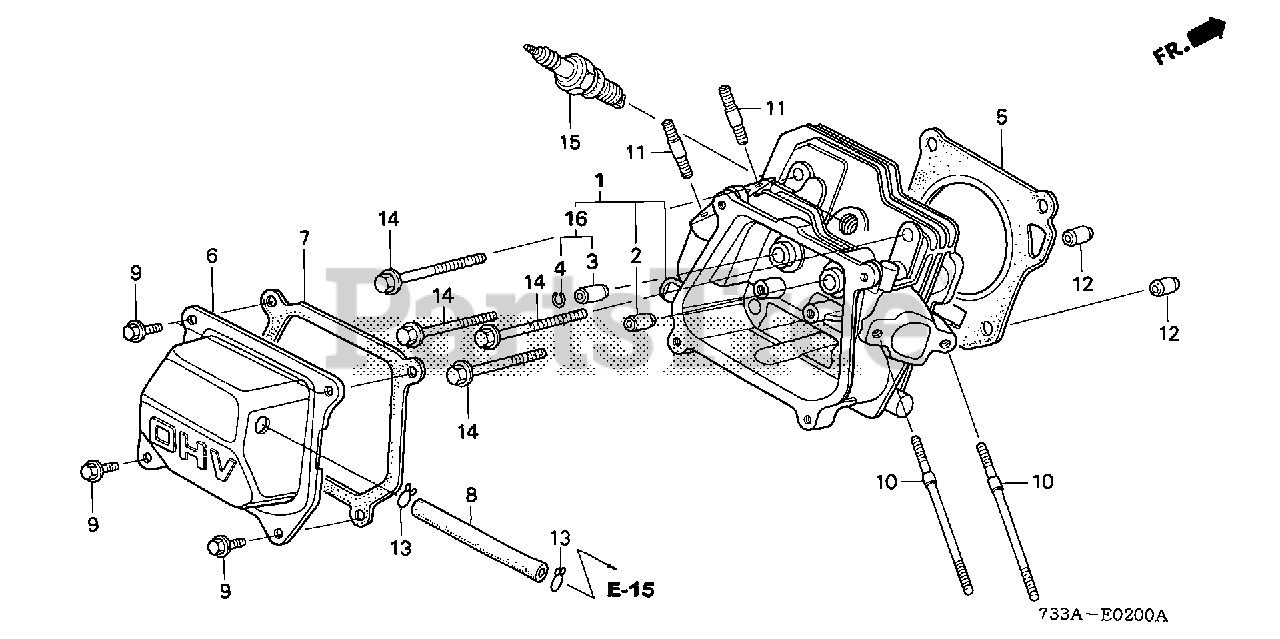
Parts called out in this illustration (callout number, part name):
1	CYLINDER HEAD
2	GUIDE, VALVE (OVER SIZE)
4	CLIP, VALVE GUIDE
5	GASKET, CYLINDER HEAD
6	COVER, HEAD
7	GASKET, HEAD COVER
8	TUBE, BREATHER
9	BOLT, FLANGE (6X12) (CT200)
9	BOLT, FLANGE (6X13) (CT200)
10	BOLT, STUD (6X112)
11	BOLT, STUD (8X32)
12	PIN, DOWEL (10X16)
14	BOLT, FLANGE (8X60)
15	SPARK PLUG (BPR5ES) (NGK)
15	SPARK PLUG (W16EPR-U) (DENSO)
15	SPARK PLUG (BPR6ES) (NGK)
15	SPARK PLUG (W20EPR-U) (DENSO)
16	GUIDE, EX. VALVE (OVER SIZE)
